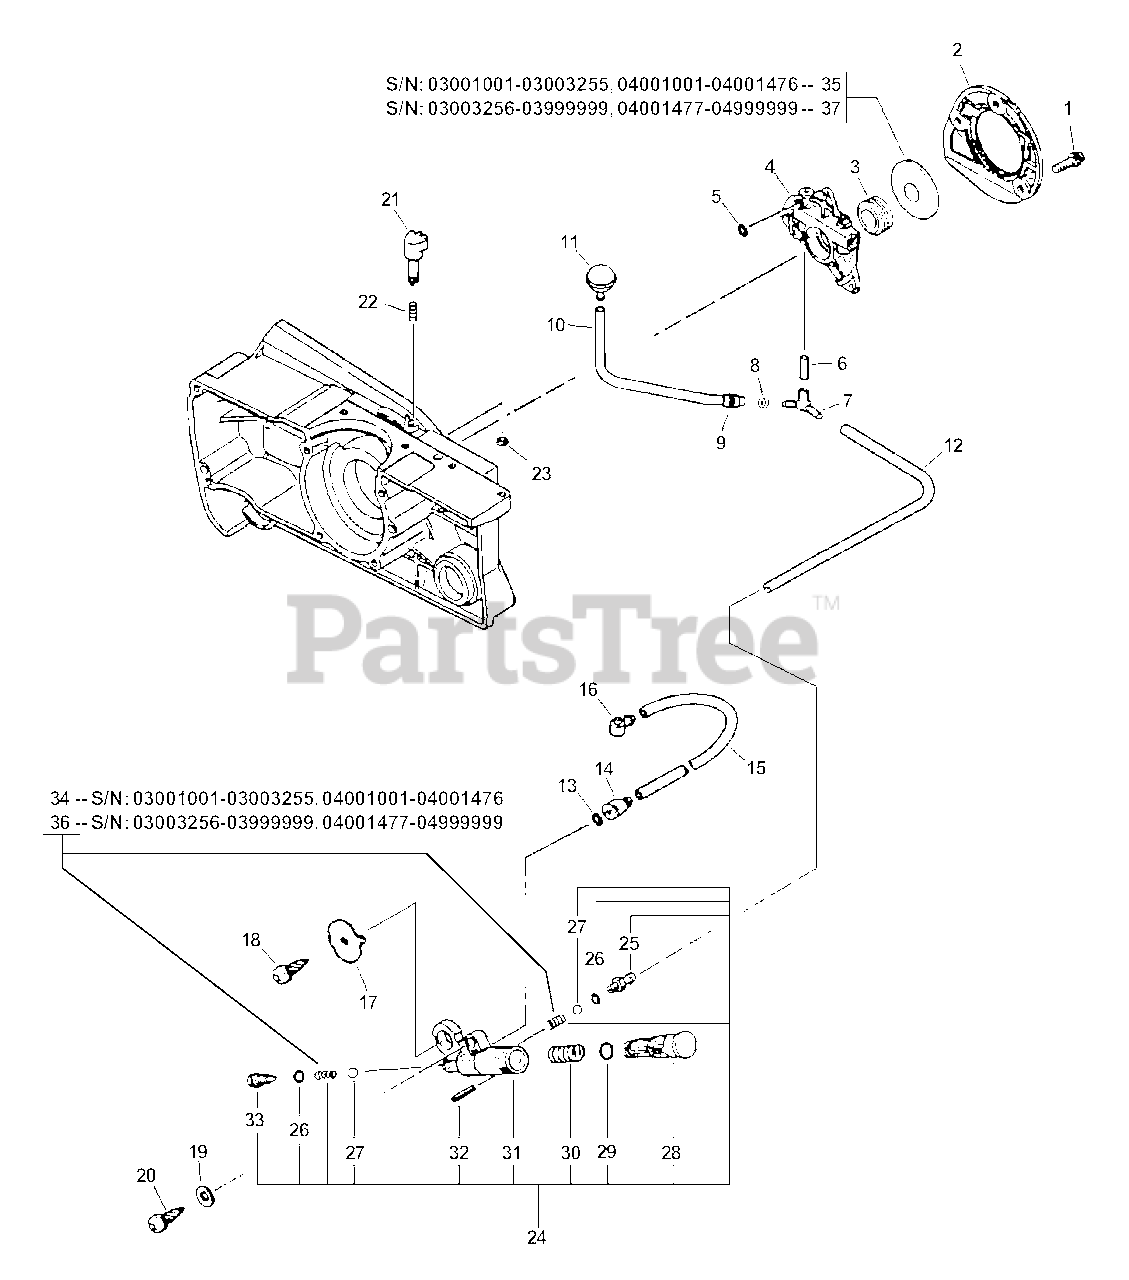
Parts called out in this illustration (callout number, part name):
1	BOLT 4×12
2	COVER, OIL PUMP - GRAY
3	GEAR, WORM
4	AUTO-OILER ASSY
5	O-RING 3
6	PIPE, OIL 3×6×20
7	CONNECTOR, PIPE
8	CLIP Ø6.5 MM
10	PIPE, OIL
11	FILTER, OIL
12	PIPE, FUEL 3×6×200
13	O-RING 3
14	CONNECTOR, PIPE
15	PIPE 3×6×125 BLACK
16	CONNECTOR, PIPE
17	BRACKET, OIL PUMP
18	SCREW 4×10
19	WASHER 5.5×12×0.8
20	SCREW 5×20
23	E-RING 3
24	OIL PUMP ASSY - ORANGE
25	CONNECTOR, PIPE
27	VALVE, BALL
28	PISTON, OIL PUMP - ORANGE
29	O-RING 7 MM
31	BODY, OIL PUMP
32	PIN, SPRING 2×16
33	ADAPTOR, OIL PUMP
34	SPRING, VALVE
35	WASHER 12
36	SPRING, COMPRESSION
37	WASHER
